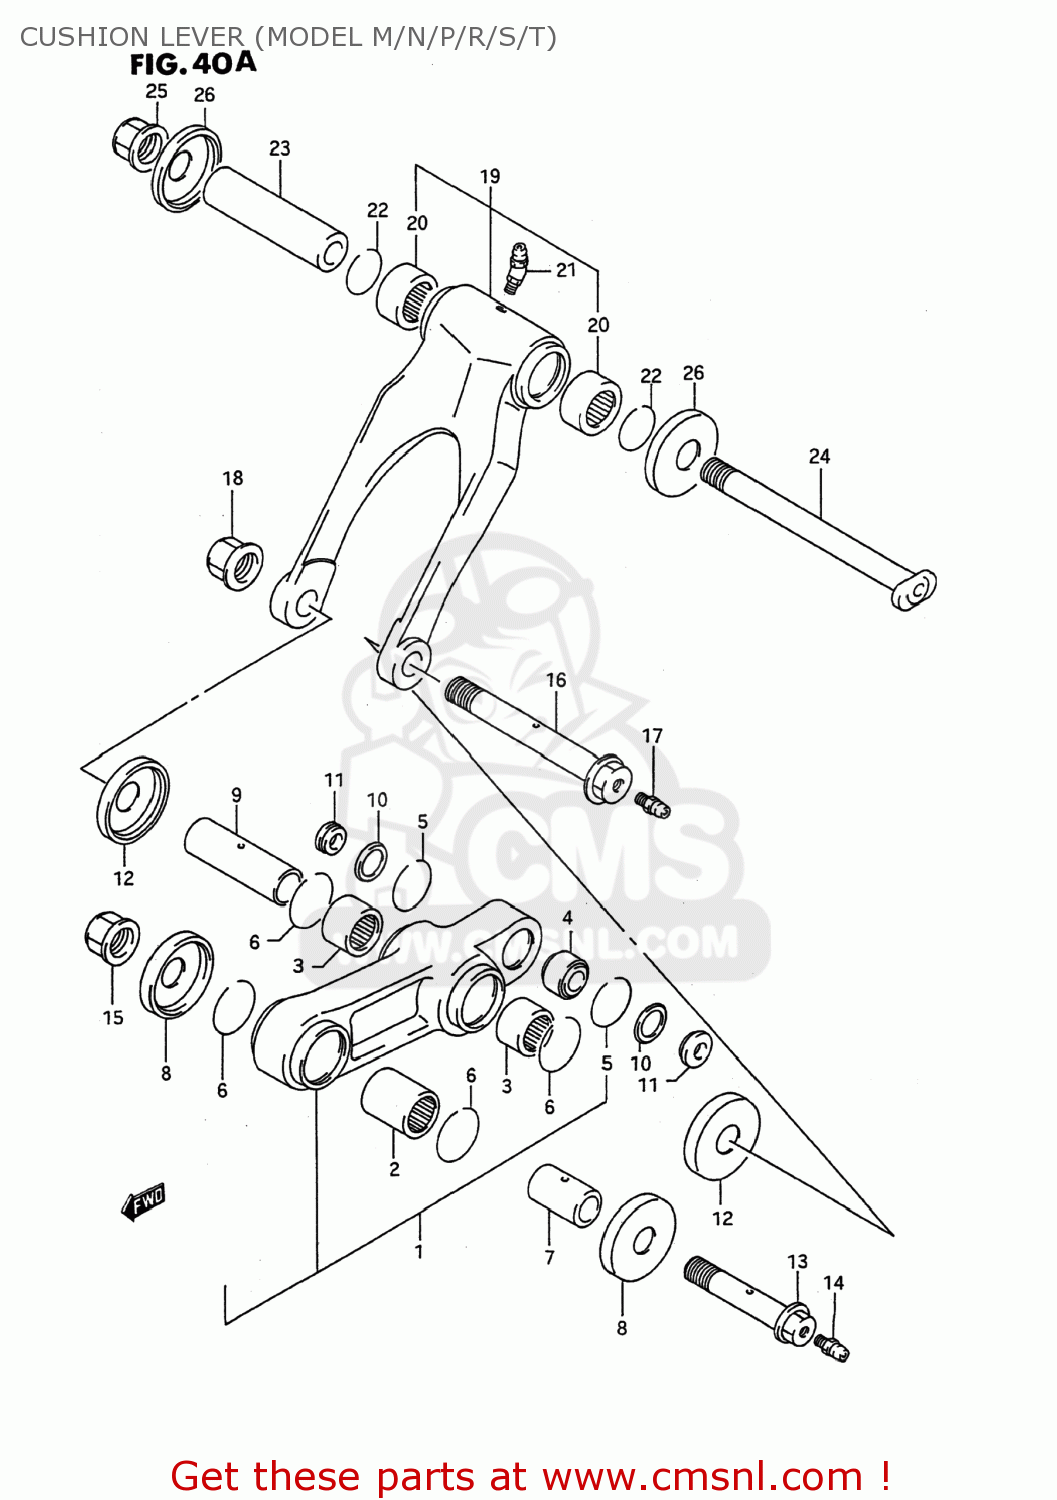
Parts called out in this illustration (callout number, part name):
1	LEVER SET,REAR CUSHION
2	BEARING(20X27X25)
3	BEARING(21X27X20)
4	BEARING,RR CUSHION LEVER
5	RING
6	CIRCLIP
7	SPACER,RR CUSHION LEVER FR
8	SEAL,REAR CUSHION LEVER
9	SPACER,RR CUSHION LEVER CTR
10	SEAL,RR CUSHION LEVER RR DUST
11	SPACER,RR CUSHION LEVER RR
12	SEAL,REAR CUSHION LEVER
13	BOLT,REAR CUSHION LEVER
14	GREASE NIPPLE
15	NUT 12MM
16	BOLT,RR CUSHION LEVER CTR
17	GREASE NIPPLE
18	NUT
19	LEVER SET,REAR CUSHION
20	BEARING(21X27X20)
21	NIPPLE,GREASE
22	CIRCLIP
23	SPACER,RR CUSHION ROD
24	BOLT,RR CUSHION ROD
25	NUT
26	SEAL,REAR CUSHION LEVER
